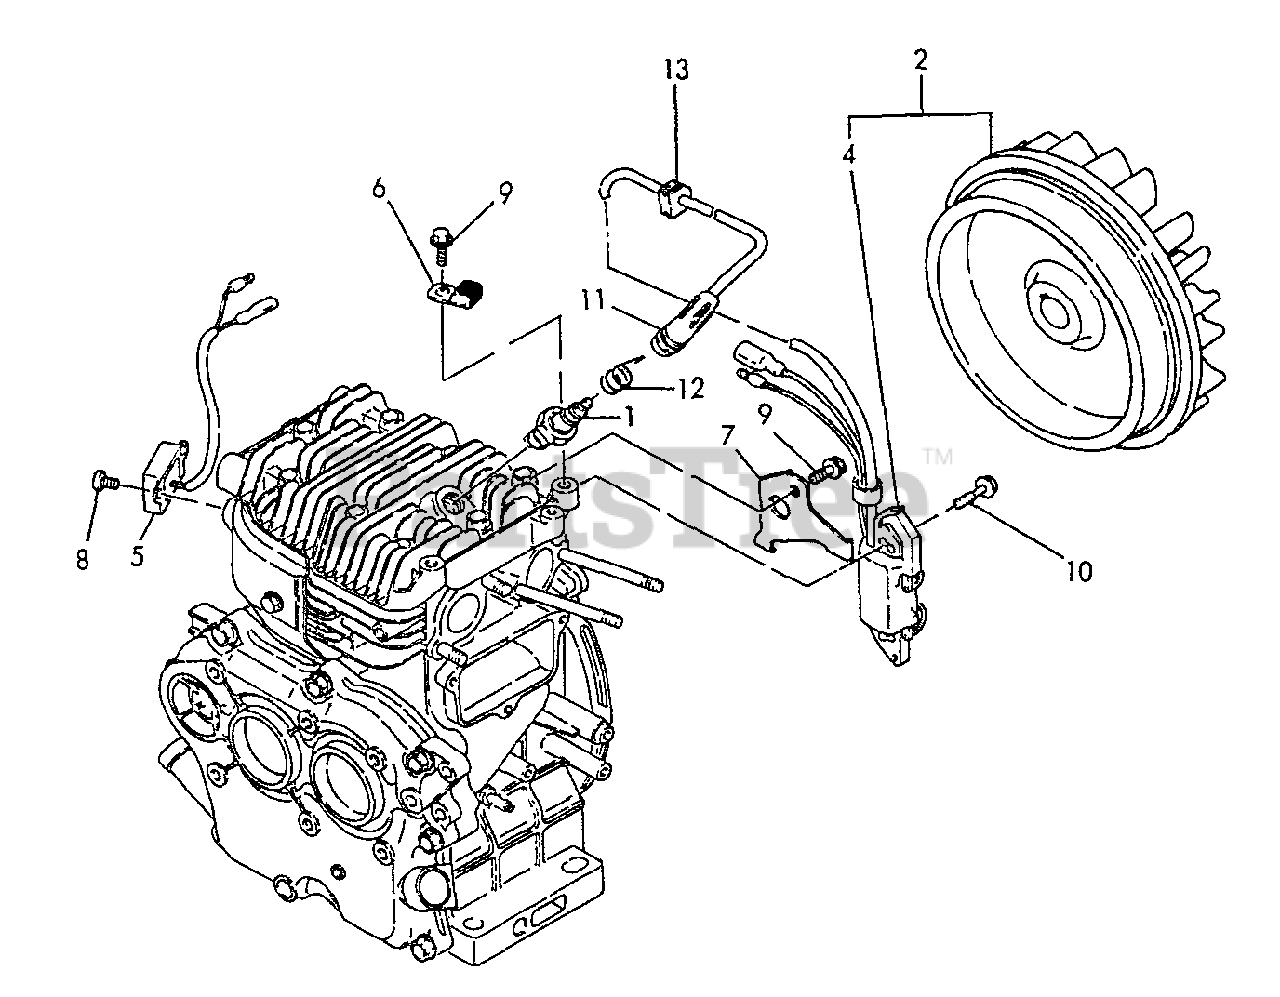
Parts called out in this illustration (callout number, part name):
1	SPARK PLUG
2	FLYWHEEL W/MAGNET
4	COIL, IGNITION
5	IGNITER
6	CLAMP
7	CLAMP
8	SCREW - 5X10
9	BOLT - 6X8 -- PLATED
10	BOLT - 6X25
11	CAP, PLUG
12	TERMINAL, SPARK PLUG CAP
13	GROMMET
